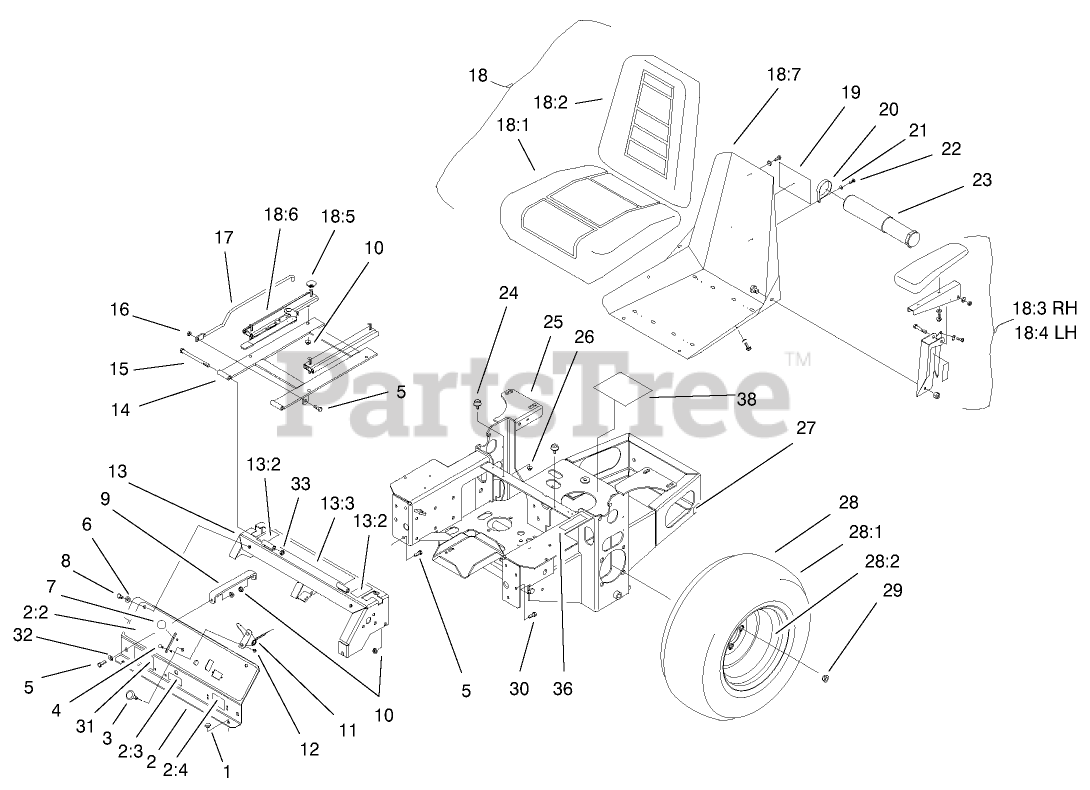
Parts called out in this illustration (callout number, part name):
1	Bumper
2	CONTROL PANEL ASM
2:2	DECAL-PANEL, CONTROL
2:3	Decal-Fuel Valve
2:4	DECAL-PROTECTION, EAR
3	Cable-Choke
4	Bolt-CARR
5	SCREW-HH
6	WASHER-PLAIN
7	Knob
8	SCREW-HH
9	Bracket-Panel,Instrument
10	NUT-HF
11	Cable
12	NUT-LOCK, NI
13	CONSOLE ASM
13:2	Decal-Motion Control
13:3	Decal-Battery
14	Frame-Seat
15	SCREW-HH
16	NUT-LOCK, NI
17	Rod-Hold Up, Seat
18	Seat ASM
18:1	Cushion
18:2	Cushion
18:3	Armrest
18:4	Armrest
18:5	Spacer-Track
18:6	Track-Locking
18:7	Frame-Seat
19	DECAL
20	CLAMP-R
21	WASHER-FLAT
22	SCREW-HWHTF
23	TUBE-MANUAL
24	Bumper
25	Frame-Main
26	NUT-HF
27	DECAL-SURFACE, HOT
28	Wheel And Tire ASM
28:1	Tire
28:2	Wheel
29	Nut
30	SCREW-HH
31	DECAL
32	WASHER-FLAT
33	NUT-LOCK, NI
36	Decal-Drive Wheel
38	Decal Hazardous Mat.
